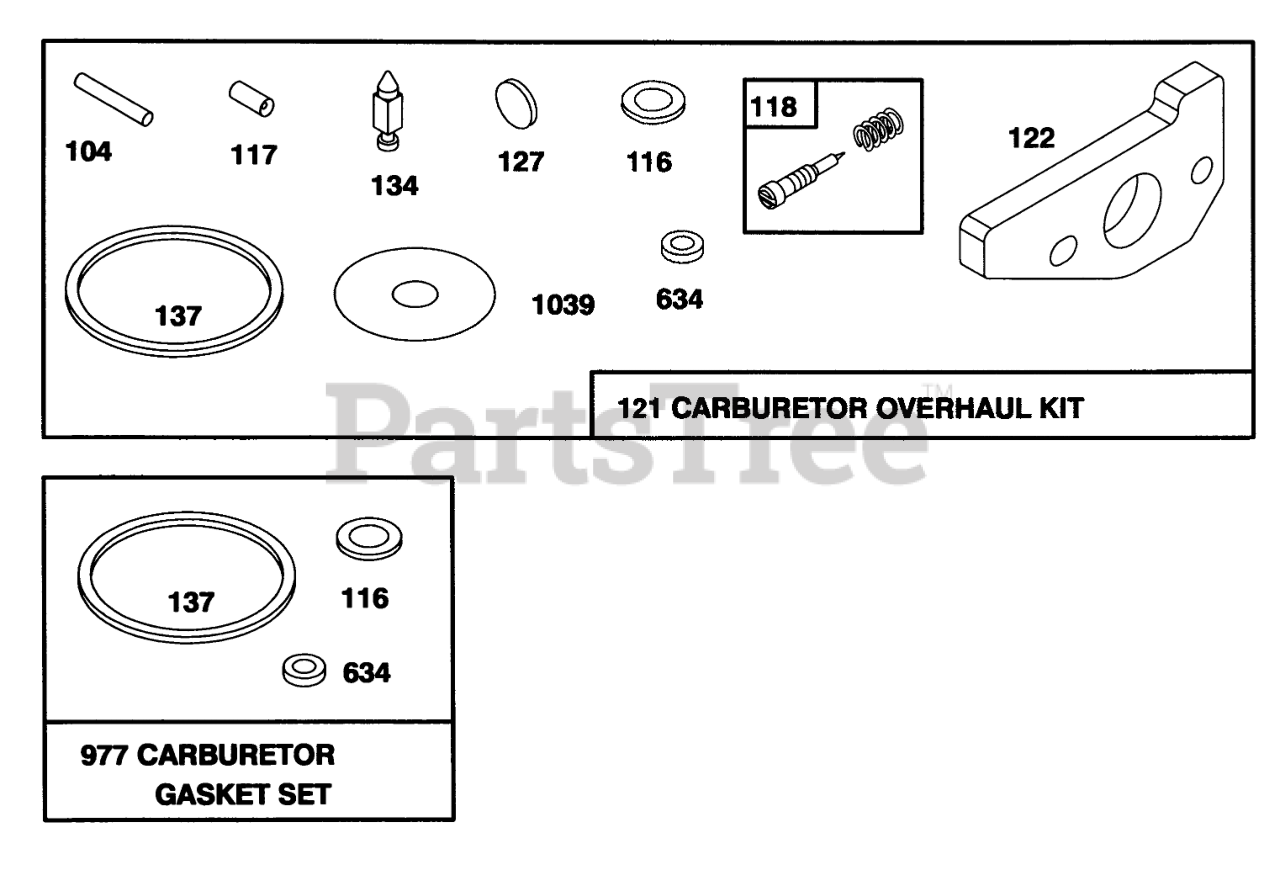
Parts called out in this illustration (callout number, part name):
104	FLOAT HINGE PIN
116	SEALING GASKET
118	VALVE KIT - NEEDLE
121	CARBURATOR OVERHAUL KIT
122	ADAPTER ASSEMBLY
134	Valve-Float (Includes Seat)
137	FLOAT BOWL GASKET
358	GASKET SET
634	SEAL WASHER
977	CARBURATOR GASKET SET
1039	FLOAT LIMITER
